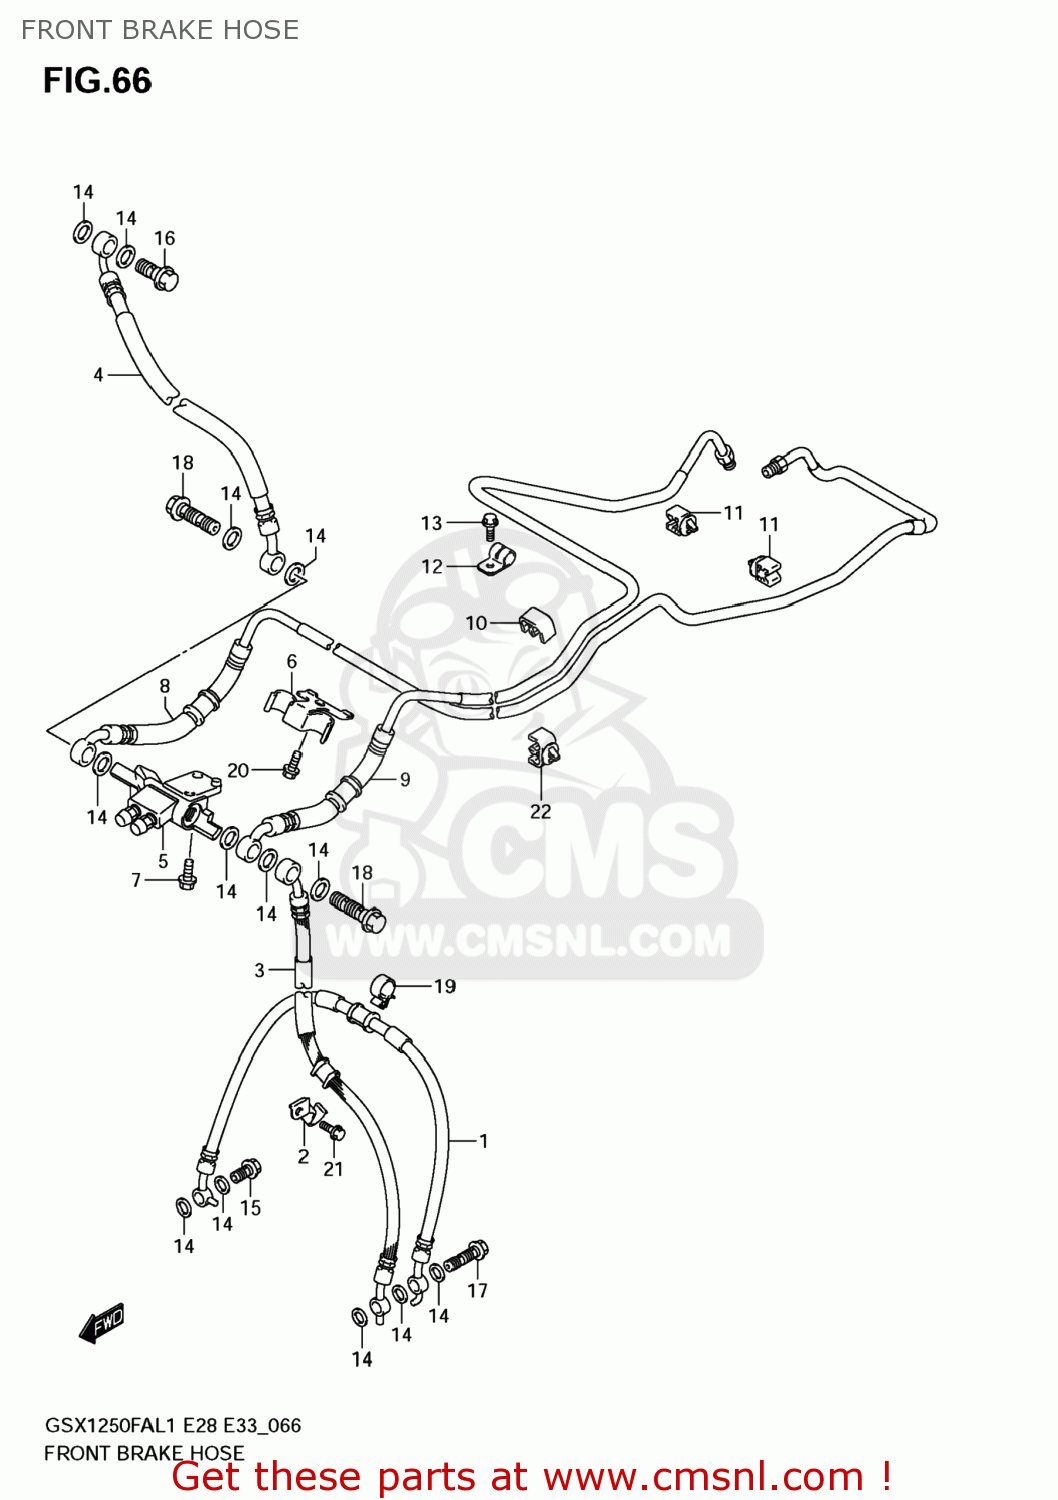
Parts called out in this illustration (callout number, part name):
1	HOSE,FR BRAKE NO.2
2	CLAMP,FR BRAKE HOSE NO.2,L
3	HOSE,FR BRAKE NO.2,L
4	HOSE,FR BRAKE NO.1
5	JOINT ASSY,FR BRAKE HOSE
6	CLAMP,FR BRAKE JOINT HOSE
7	BOLT
8	HOSE ASSY,FR BRAKE NO.1
9	HOSE ASSY,FR BRAKE NO.2
10	CLAMP
11	CLAMP,BRAKE PIPE AXLE NO.2
12	CLAMP
13	BOLT
14	WASHER(10X15X1.5)
15	BOLT UNION
16	BOLT UNION
17	BOLT UNION
18	BOLT UNION
19	CLAMP
20	BOLT
21	BOLT
22	CLAMP
